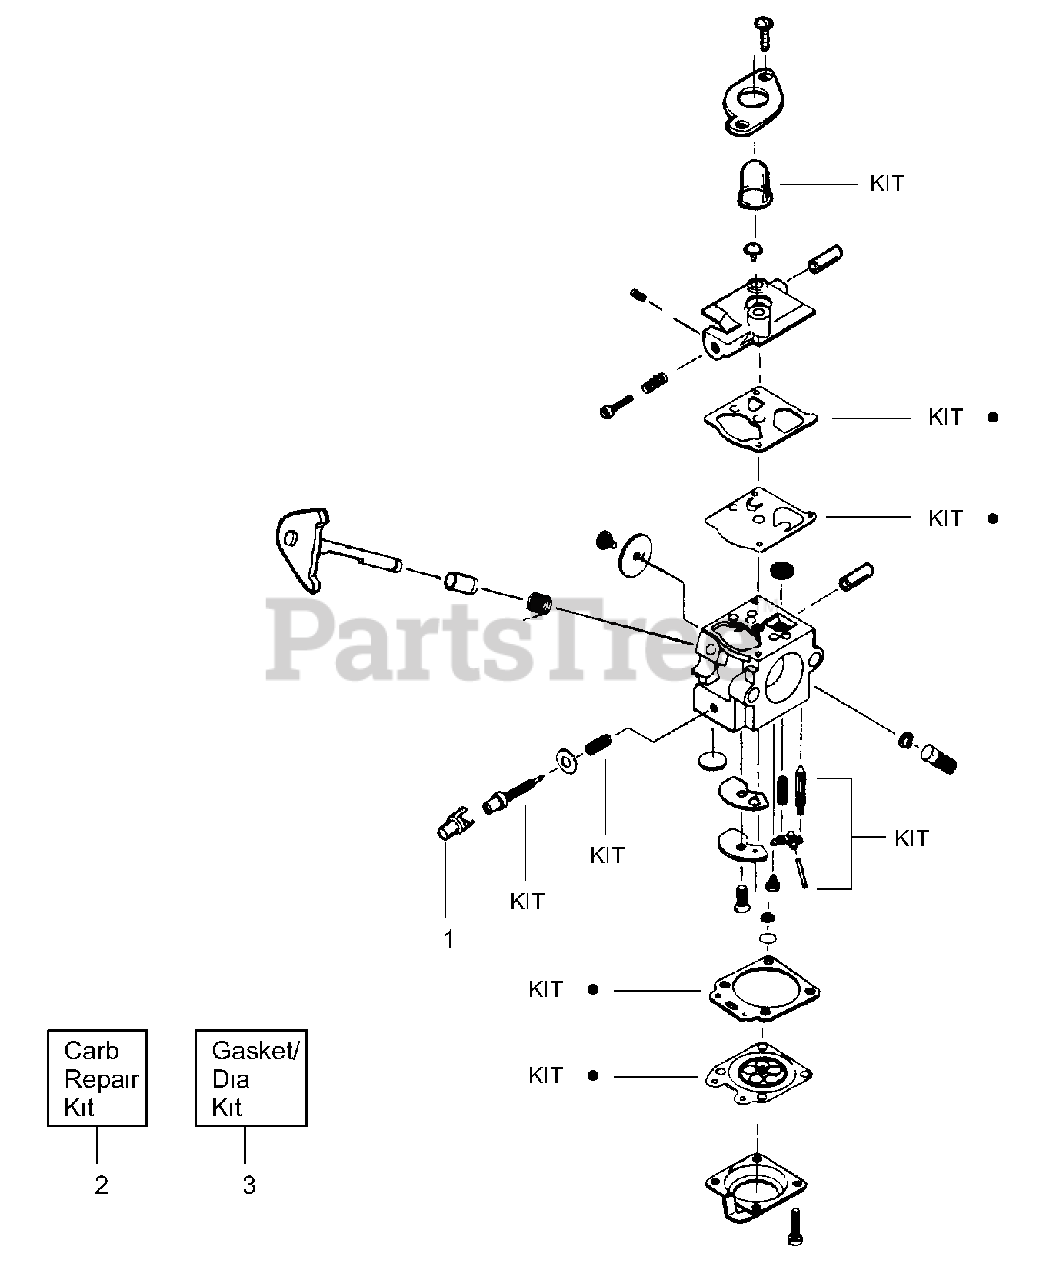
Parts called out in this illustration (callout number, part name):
1	Limiter Cap
2	Carburetor Repair Kit - Walbro
2	Carburetor Repair Kit - Zama
3	Gasket Diaphragm Kit - Walbro
3	Gasket Diaphragm Kit - Zama
